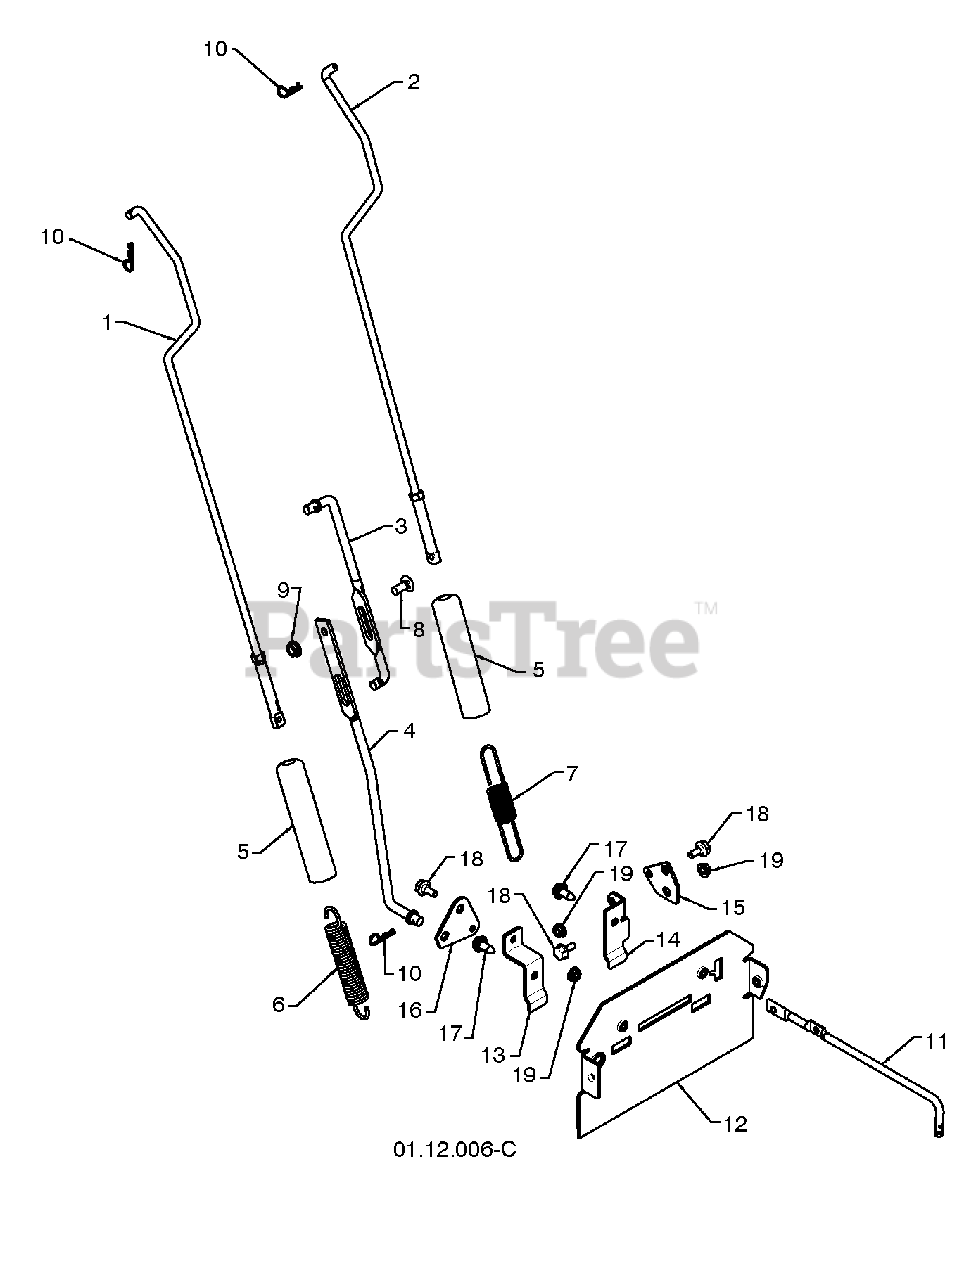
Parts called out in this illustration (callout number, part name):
1	IMPELLER ROD ASSEMBLY
2	TRACTION ROD ASSEMBLY
3	SHIFTER ROD TOP
4	SHIFTER ROD BOTTOM
5	SPRING SLEEVE
6	IMPELLER SPRING
7	TRACTION SPRING
8	CARRIAGE BOLT 5/16-18 X .750
9	NUT 5/16-18
11	CLUTCH ROD
12	REAR PLATE
13	SHIFTER PLATE BRACKET
14	CLUTCH PLATE BRACKET
15	CLUTCH PLATE
16	SHIFTER PLATE
17	BOLT 5/16-18 X .750
18	SHOULDER BOLT 1/4-20 X .500
19	NUT 1/4-20
